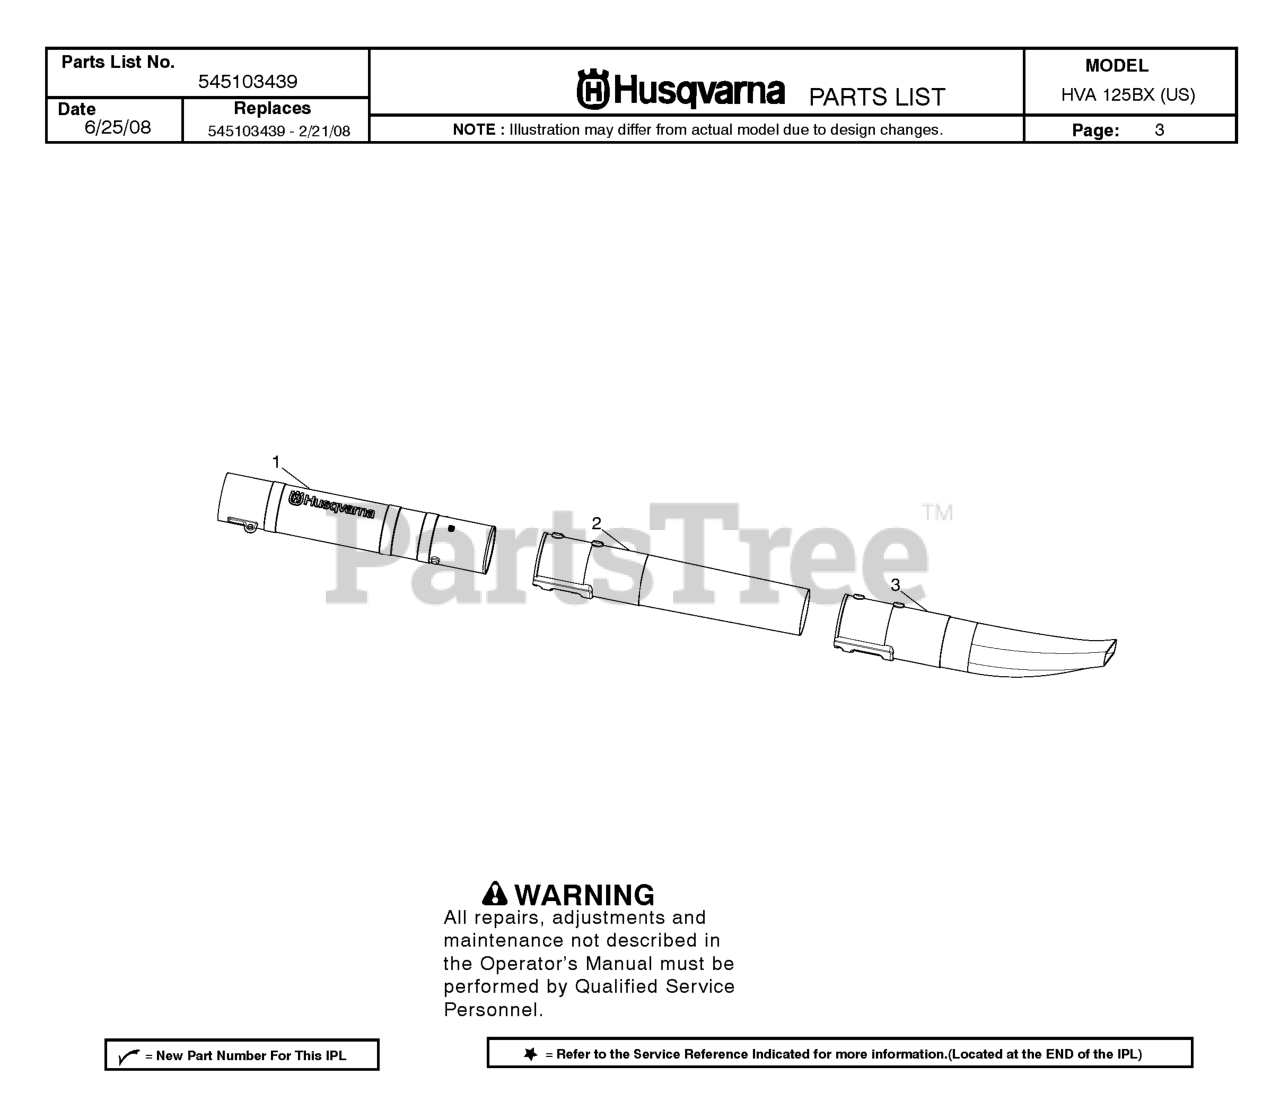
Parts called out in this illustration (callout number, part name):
1	ASSY TUBE BLOWER W/BARR
2	TUBE, LOWER
3	FLARE, LOWER TUBE
